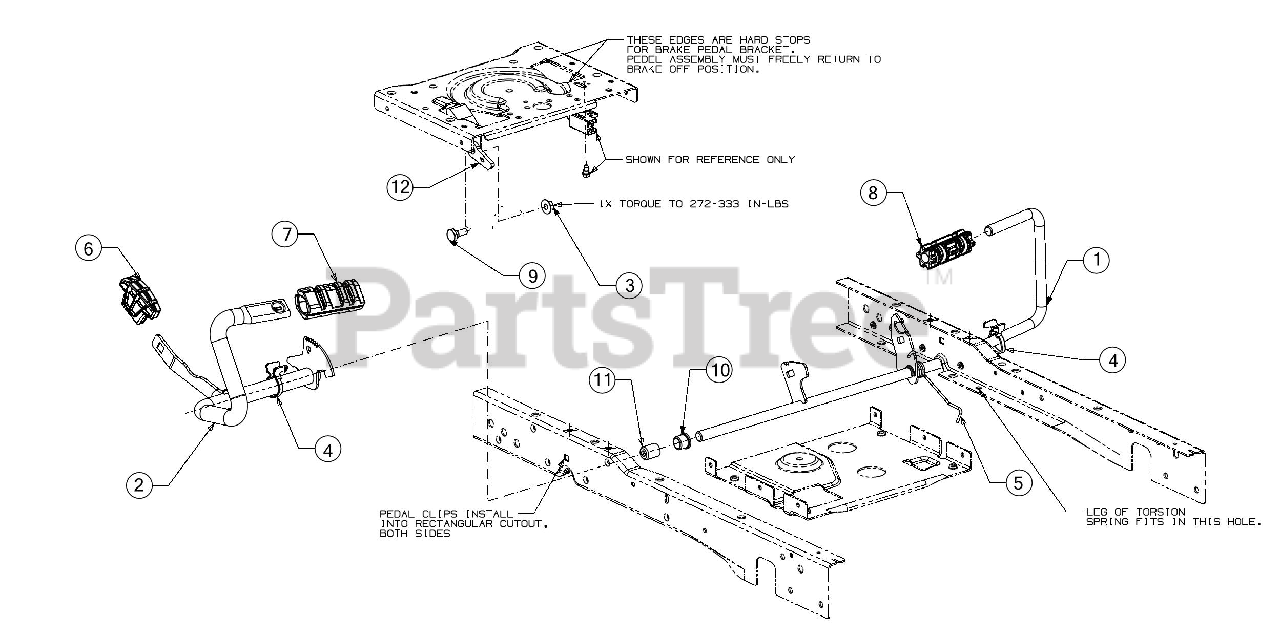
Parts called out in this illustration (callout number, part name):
1	BRAKE PEDAL ASSEMBLY
2	FORWARD/REVERSE PEDAL ASSEMBLY
3	FLANGE LOCK NUT
5	TORSION SPRING
6	REVERSE PEDAL PAD
7	FORWARD PEDAL PAD
8	BRAKE PEDAL PAD
9	SHOULDER SCREW
10	FLANGE BEARING .63X.84X.71
11	PLASTIC SLEEVE BEARING
12	CRUISE LATCH
